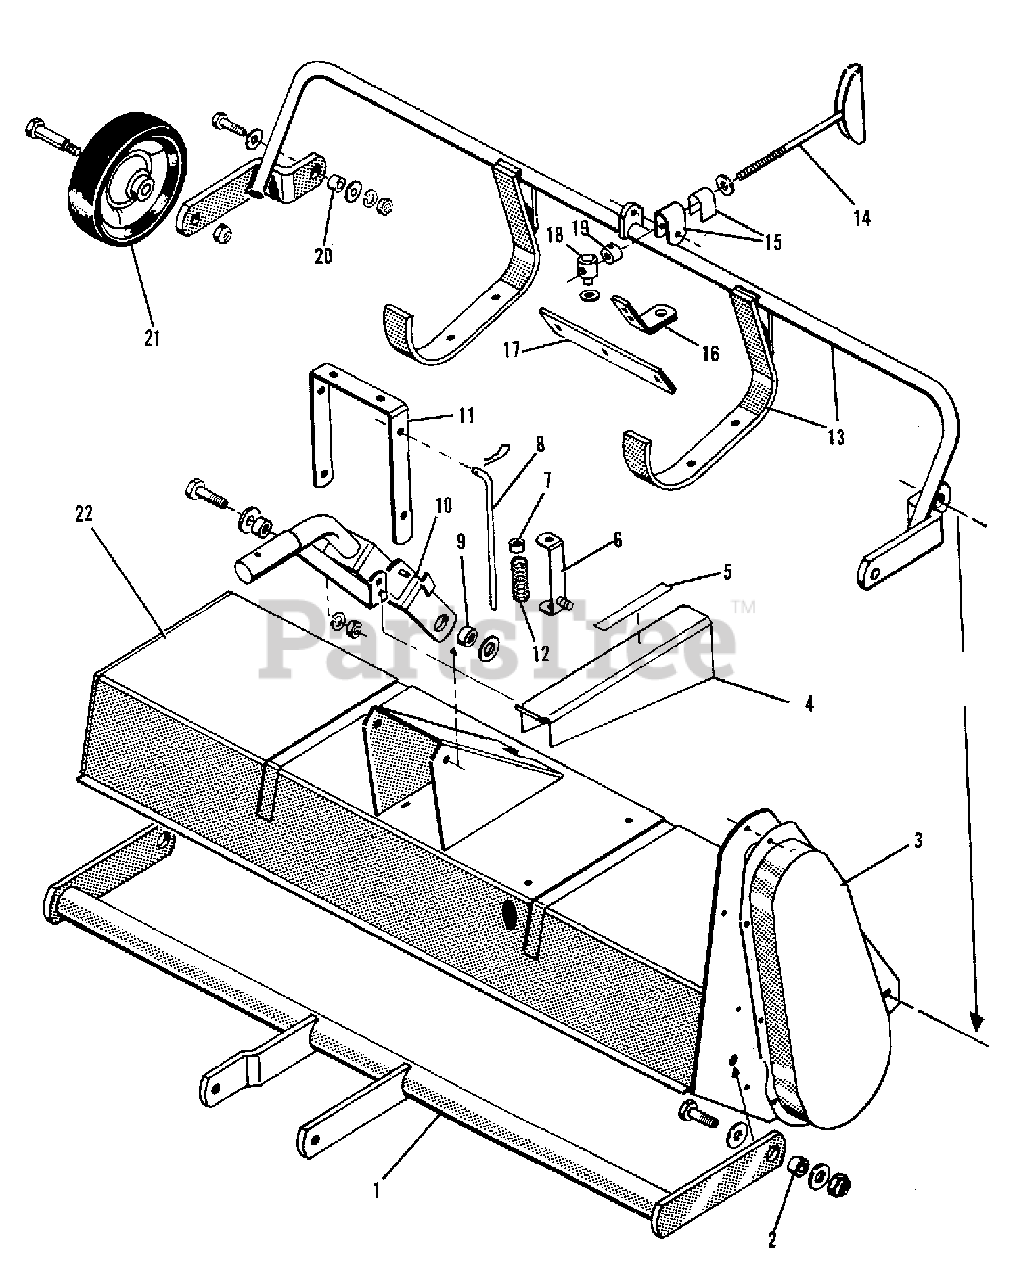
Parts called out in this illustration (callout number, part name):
1	HITCH ASSEMBLY, Thatcher
2	CAPSCREW, 1/2NC x 1-1/4
2	WASHER, 1/2, Plain
2	NUT, 1/2NC, Lock
3	GUARD, Chain
3	SCREW, 1/4NC x 3/8, Taptite
4	GUARD, Belt
4	BOLT, 5/16NC x 3/4
4	NUT, 5/16NC, Wing
5	DECAL, Safety
6	BRACKET ASSEMBLY, Rod Guide
6	NUT, 5/16NC, Lock
7	COLLAR, Set
7	SETSCREW, 1/4NC x 3/8, Square Head
8	ROD, Clutch
8	PIN, Quick
9	CAPSCREW, 7/16NC x 3-1/2
9	LOCKWASHER, 7/16
9	NUT, 7/16NC
9	WASHER, 3/8, Plain
9	WASHER, 7/16, Plain
9	CAPSCRE, 7/16NC x 1-1/4
10	BAR ASSEMBLY, Lift
10	PIN, Round Head Hitch
10	PIN, Quick
11	HANDLE, Clutch
11	PIN, Quick
13	BAR ASSEMBLY, Adjuster
14	SCREW ASSEMBLY, Hand Control
14	WASHER, 3/8, Plain
15	GUIDE, Rod
15	LINER, Rod Guide
15	CAPSCREW, 5/16NC x 1-1/4
15	NUT, 5/16NC, Lock
17	BAR, Reinforcement
17	BOLT, 5/16NC x 1
17	BOLT, 5/16NC x 3/4
17	LOCKWASHER, 5/16
17	NUT, 5/16NC
18	PIVOT, Control
18	WASHER, 5/16
18	PIN, Cotter, 3/32 x 3/4
19	COLLAR, Set
19	SETSCREW, 1/4NC x 5/16, Socket Head
20	CAPSCREW, 3/8NC x 1-1/4
20	WASHER, 3/8, Plain
20	LOCKWASHER, 3/8
20	NUT, 3/8NC
21	WHEEL ASSEMBLY, With Tire
21	BOLT, Wheel
21	NUT, 7/16NC, Lock
22	HOUSING ASSEMBLY, 38" Thatcher
22	PLUG, Button
